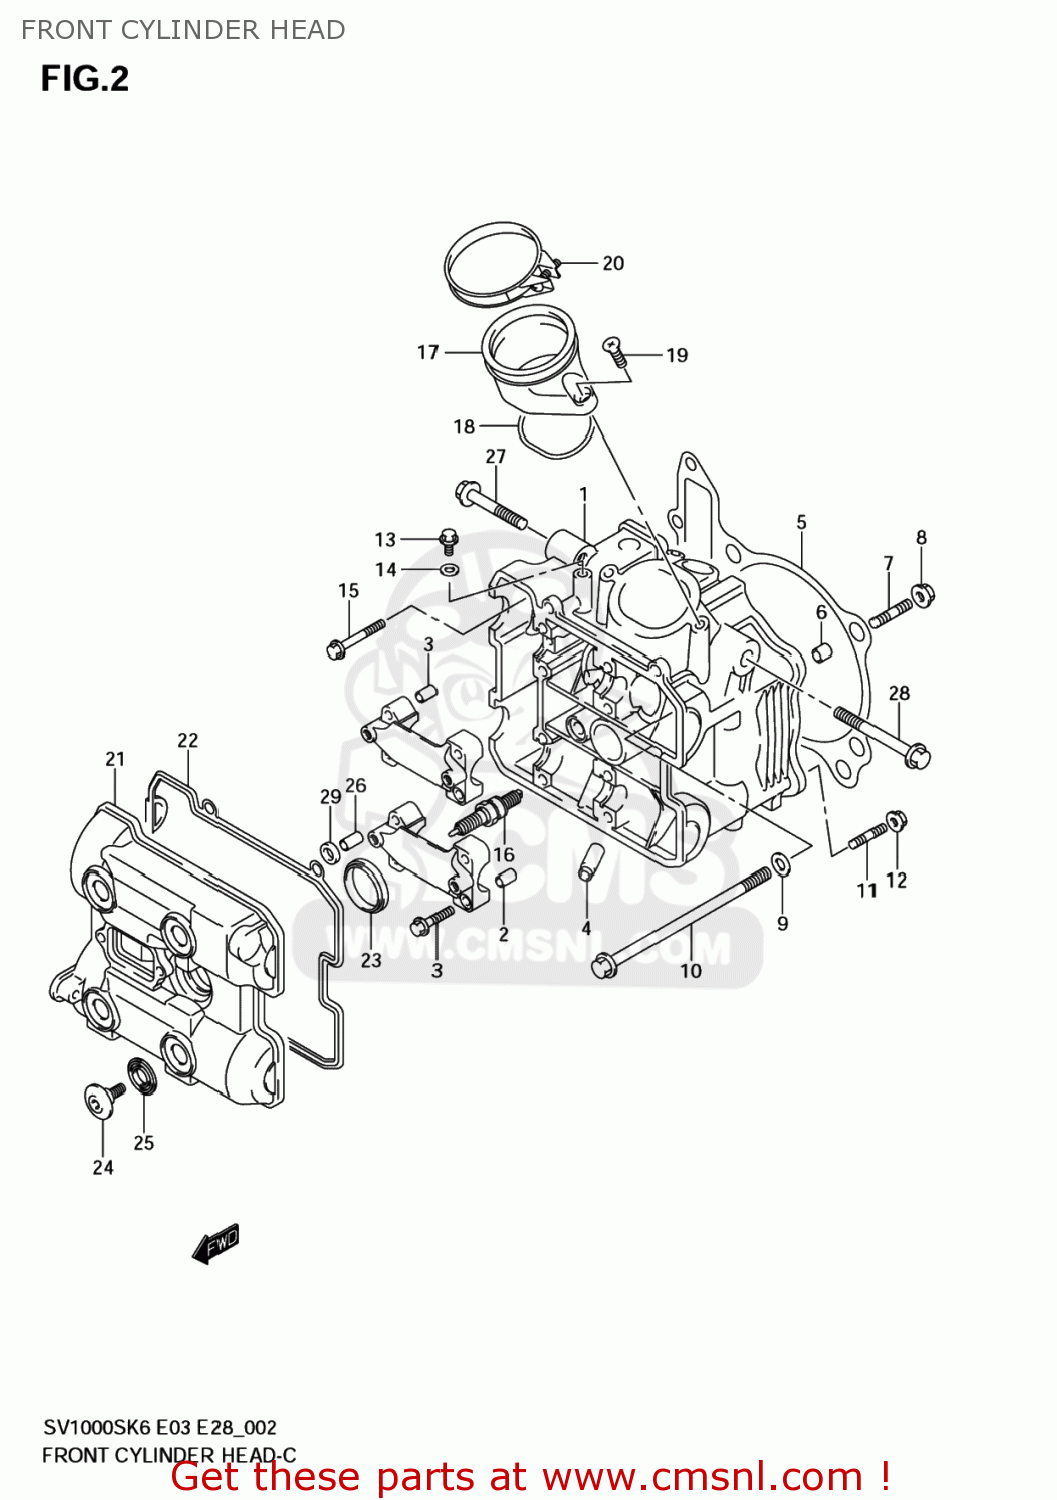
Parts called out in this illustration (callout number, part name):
1	HEAD ASSY,CYLINDER FR
2	PIN(6.2X8X11)
3	BOLT(6X39)
4	GUIDE,VALVE
5	GASKET,CYLINDER HEAD (NAS)
6	PIN
7	BOLT,STUD
8	NUT
9	WASHER(10.5X19X2)
10	BOLT(10X175)
11	BOLT,STUD
12	NUT
13	BOLT
14	GASKET(5.8X13X1.2) (NAS)
15	BOLT(6X70)
16	PLUG,SPARK(CR8EK)
17	PIPE ASSY,INTAKE FR
18	O RING(D:2.4,ID:55.6)
19	SCREW ,6X16
20	CLAMP
21	COVER,CYLINDER HEAD FR
22	GASKET,CYL HEAD COVER NO.1 (NAS)
23	GASKET,CYL HEAD COVER NO.2
24	BOLT(7X17.5)
25	WASHER(10.6X25.5X2.3)
26	PIN(6.2X8X16)
27	BOLT
28	BOLT
29	GASKET,2ND AIR PASSAGE (NAS)
